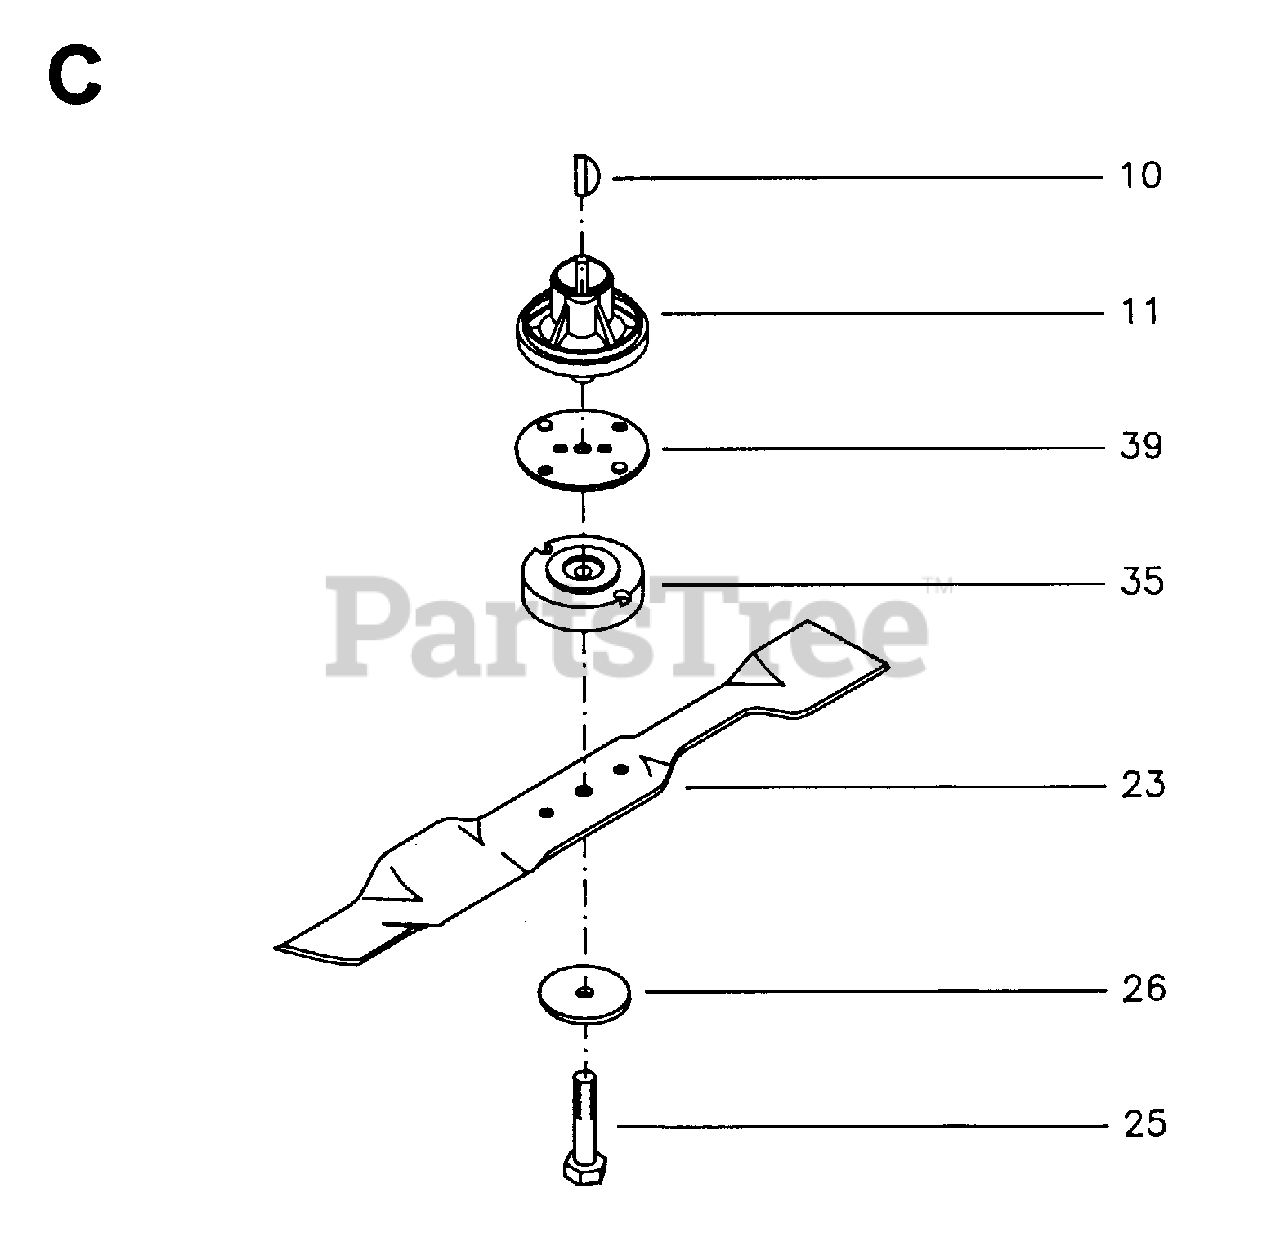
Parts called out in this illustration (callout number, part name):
11	BLADE ADAPTER
35	SPACER
39	STEEL PLATE ADAPTER
